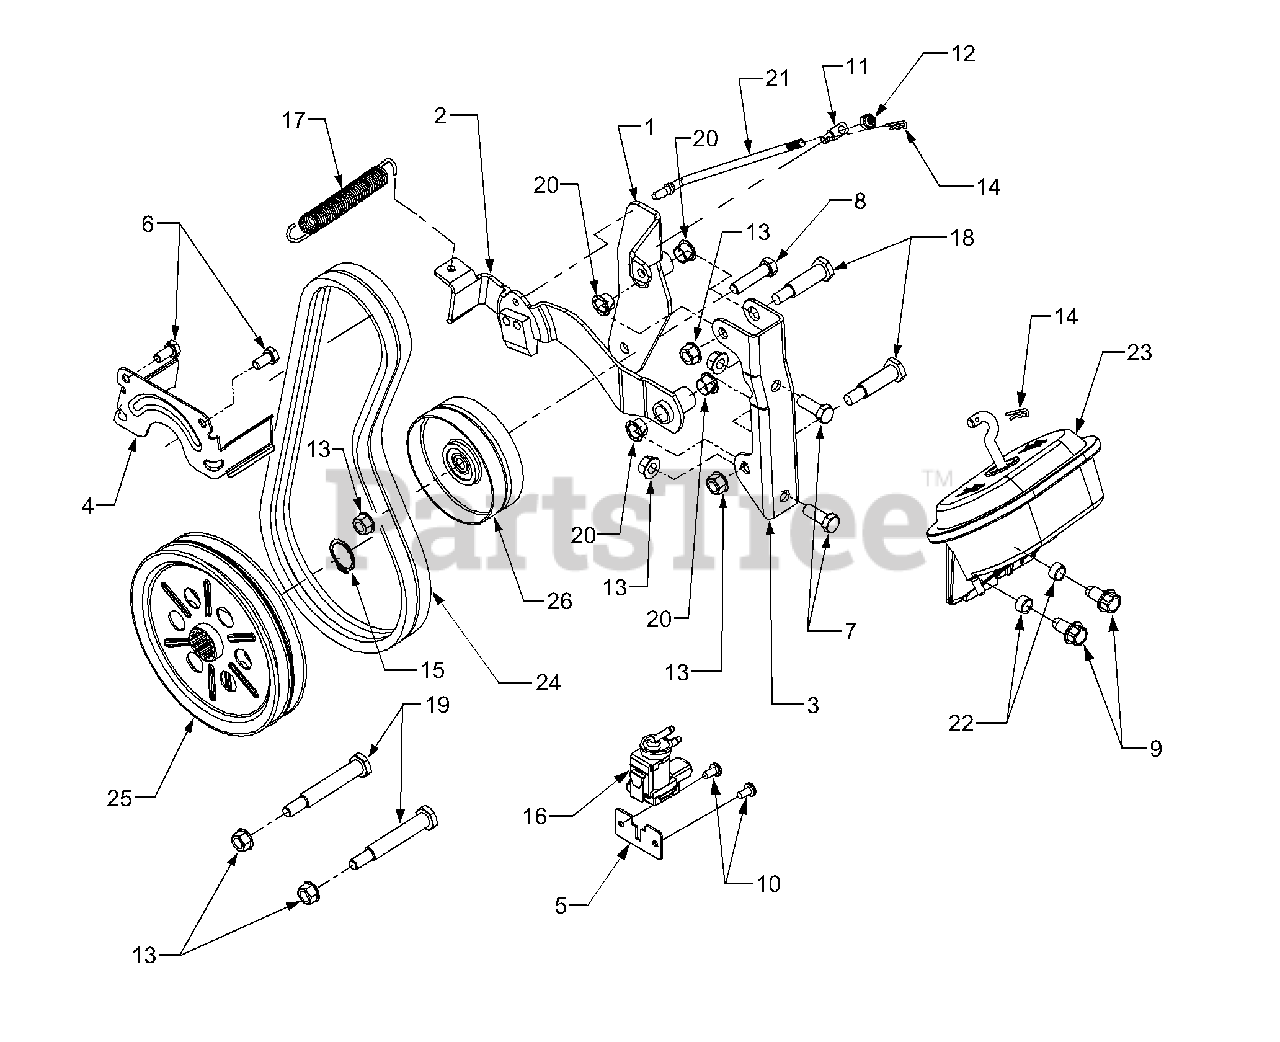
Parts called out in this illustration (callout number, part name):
1	Bracket, Idler
2	Bracket Assembly, Brake
3	Bracket, PTO Mounting
5	Bracket, Solenoid Mounting
6	Screw, Hex Cap 5/16-24 x .625 GR5
7	Screw, Hex Cap 3/8-16 x 1.0 GR5
8	Screw, Hex Cap 3/8-16 x 1.5 GR5
9	Screw, Hex Wash. Hd. Tapp 3/8-16 x .75
10	Screw, Phil. Hd. Tapp #12-14 x .5
11	Ferrule, Brake Adjustment
12	Nut, Hex Insert Lock, 1/4-20
13	Nut, Flange Lock, 3/8-16
14	Pin, Internal Cotter
15	Snap Ring, 1.0 Dia Shaft
16	Solenoid, Kit Vacuum Actuator
17	Spring, Extension, .530 x 4.74
18	Shoulder Screw, .498 x 1.45
19	Shoulder Screw
20	Bearing, Nylon Flange
21	Rod, PTO Brake
22	Spacer, .380 x .5 x .265
23	Vacuum Actuator
24	V-Belt, A-Section x 37.63 (Set of two belts)
25	Pulley, PTO Drive. 6.75-Double
26	Pulley, Flat Idler, 4.0
